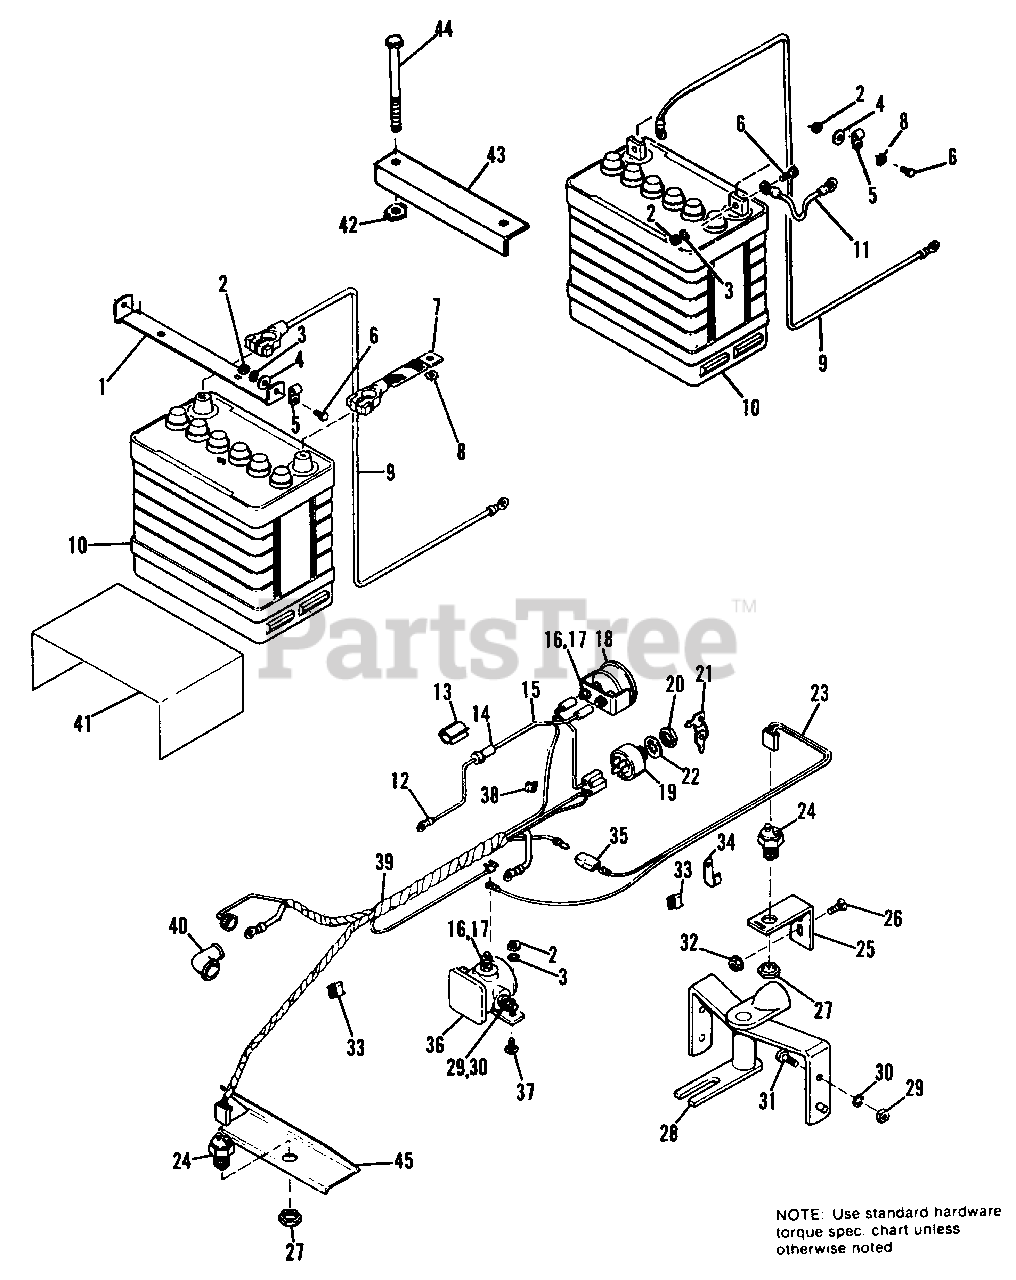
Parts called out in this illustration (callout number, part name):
1	HOLD DOWN Battery (1690020 & 1690106 Only)
2	NUT, Hex, 1/4 (Qty. 4 on 1690020, 1690106)
3	LOCKWASHER 1/4 (Qty. 4 on 1690020, 1690106)
4	WASHER, Plain 1/4 (Qty. 1 on 1690019 Only)
7	CABLE, Battery to Ground (1690020 & 1690106)
8	LOCKWASHER, Int., 1/4
9	CABLE, Battery to Solenoid (1690020 & 1690106)
9	CABLE, Battery to Solenoid
10	BATTERY KIT (1690020 & 1690106 Only)
10	BATTERY KIT
11	CABLE (1690019 Only)
12	WIRE, Solenoid to Negative
13	CLIP, Fuse
14	FUSE, 7-1/2 amp
15	WIRE, Negative Ammeter to Solenoid
16	LOCKWASHER, #10
17	NUT, Hex, Full, #10-32
19	SWITCH, Ignition
20	NUT, Special
22	LOCKWASHER, Int., 5/8
23	WIRE, Safety Swtich
24	SWITCH, Safety
26	BOLT, Carriage, 1/4-20 x 3/4
27	NUT, Pal, 9/16-18
28	PIVOT ASSY.
29	NUT, Hex, Full, 5/16-18
30	LOCKWASHER, 5/16
31	CAPSCREW, Hex Hd., 5/16-18 x 3/4
32	LOCKNUT, Flange, 1/4-20
33	CLIP, Speed
34	J-CUP, Open
35	CONNECTOR, Insulator
37	BOLT, Carriage, 1/4-20 x 5/8
38	CLIP, Cable
39	HARNESS ASSY.
40	COVER, Terminal
41	INSULATION, Battery
42	NUT Retainer 1/4-20 (1690019 Only)
43	HOLD DOWN, Battery (1690019 Only)
44	CAPSCREW, Hex Hd., 1/4-20 x 7 (1690019 Only)
45	SHIELD, Heat (1690020 & 1690106 Only)
